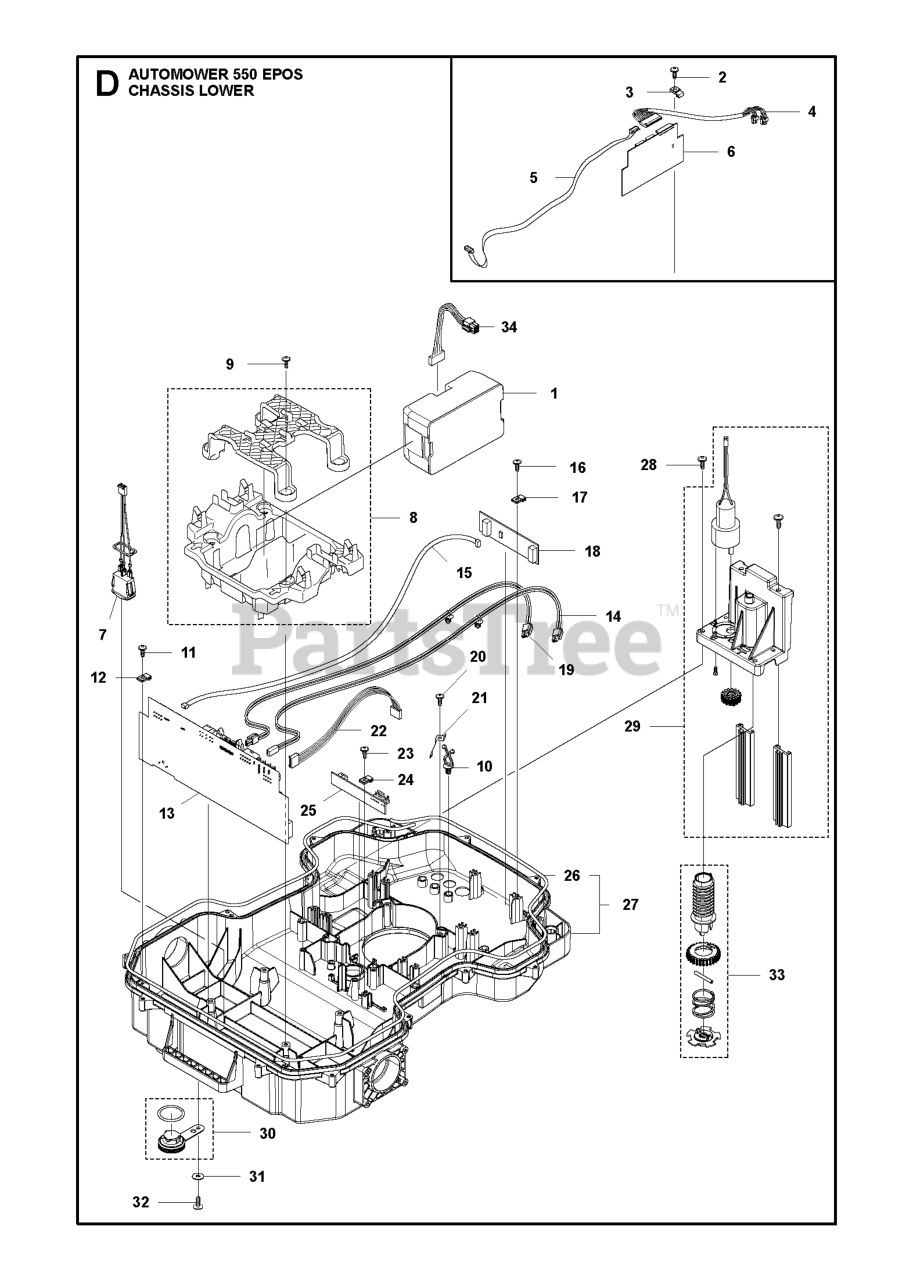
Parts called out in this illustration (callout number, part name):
1	BATTERY
2	SCREW 14MM
3	CLAMP PCB
4	Wires
5	LOOM AUX
6	PRINTED CIRCUIT ASSY ULTRASONI
7	LOOM ON/ OFF
8	HOLDER KIT BATTERY
9	SCREW ITXPANT
10	HOLDER TWIST LOCK
11	SCREW 14MM
12	CLAMP PCB
13	PRINTED CIRCUIT ASSY PCBA MAIN
14	WIRING ASSY LED LIGHT EXTENSIO
15	LOOM LOOP SENSOR
16	SCREW 14MM
17	CLAMP PCB
18	PRINTED CIRCUIT ASSY LOOP SENS
19	LOOM CHARGING LINK HIGH CHARGI
20	SCREW 14MM
21	SPRING GUIDE HEIGHT ADJUSTMENT
22	LOOM HEIGHT ADJUSTMENT
23	SCREW 14MM
24	CLAMP PCB
25	PRINTED CIRCUIT ASSY PCBA CUTT
26	SEALING STRIP
27	CHASSIS KIT LOWER
28	SCREW 14MM
29	MOTOR ASSY HEIGHT MOTOR
30	PLUG KIT
31	WASHER
32	SCREW ITXPANT
33	SCREW KIT
34	WIRING ASSY BATTERY CABLE
